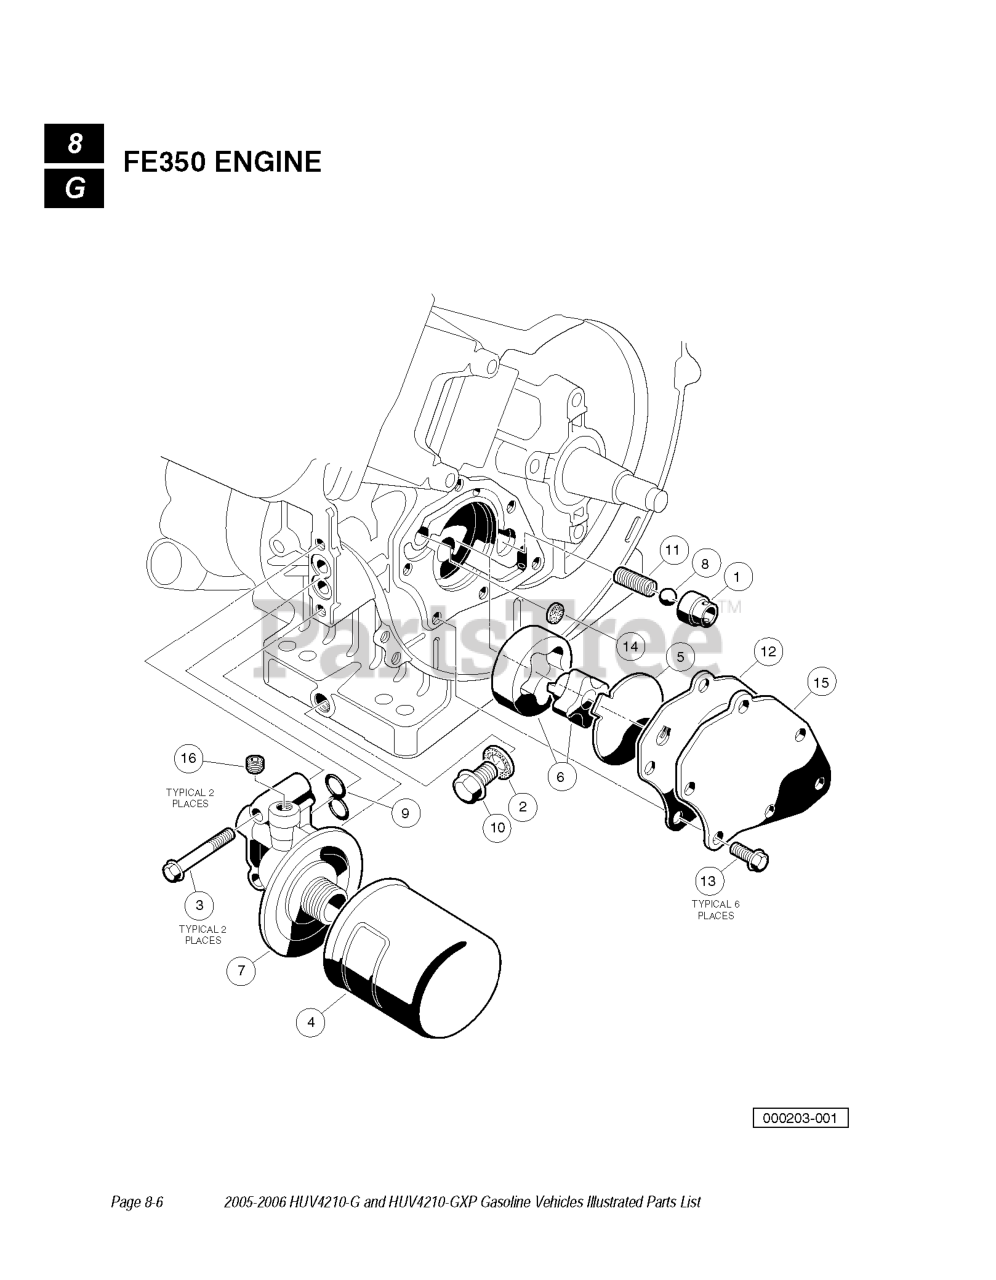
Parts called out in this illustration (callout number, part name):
1	SEAT, VALUE OIL PRESS RELIEF
2	GASKET, DRAIN PLUG
3	BOLT, FLANGED
4	FILTER, OIL
5	PLATE - OIL - PUMP
6	OIL PUMP AND ROTOR
7	BRACKET - OIL FILTER MOUNT
8	BALL, STEEL, PRESS, RELIEF
10	PLUG, DRAIN FE290D
13	BOLT - FLANGED SMALL
15	COVER - PUMP
